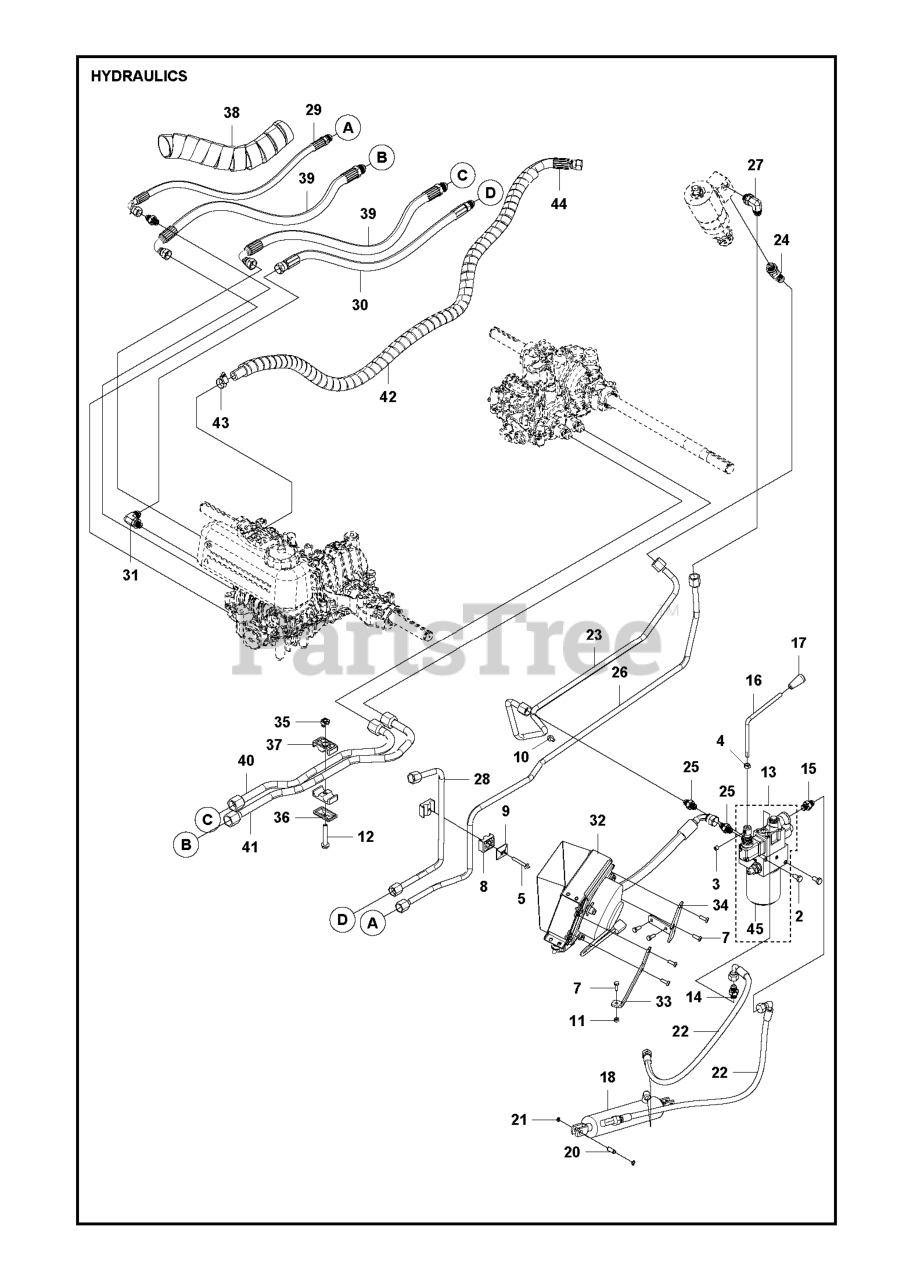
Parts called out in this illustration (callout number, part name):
2	BOLT - M8X16
4	NUT
7	BOLT FLANGE - M6X20
8	PIPE CLAMP
11	LOCKNUT M6
12	SCREW EHHFM
21	RETAINING RING SGA 10
36	COVER PLATE
37	PIPE CLAMP
38	HOSE GUARD D=43 L=400
42	HOSE GUARD
45	OIL FILTER
